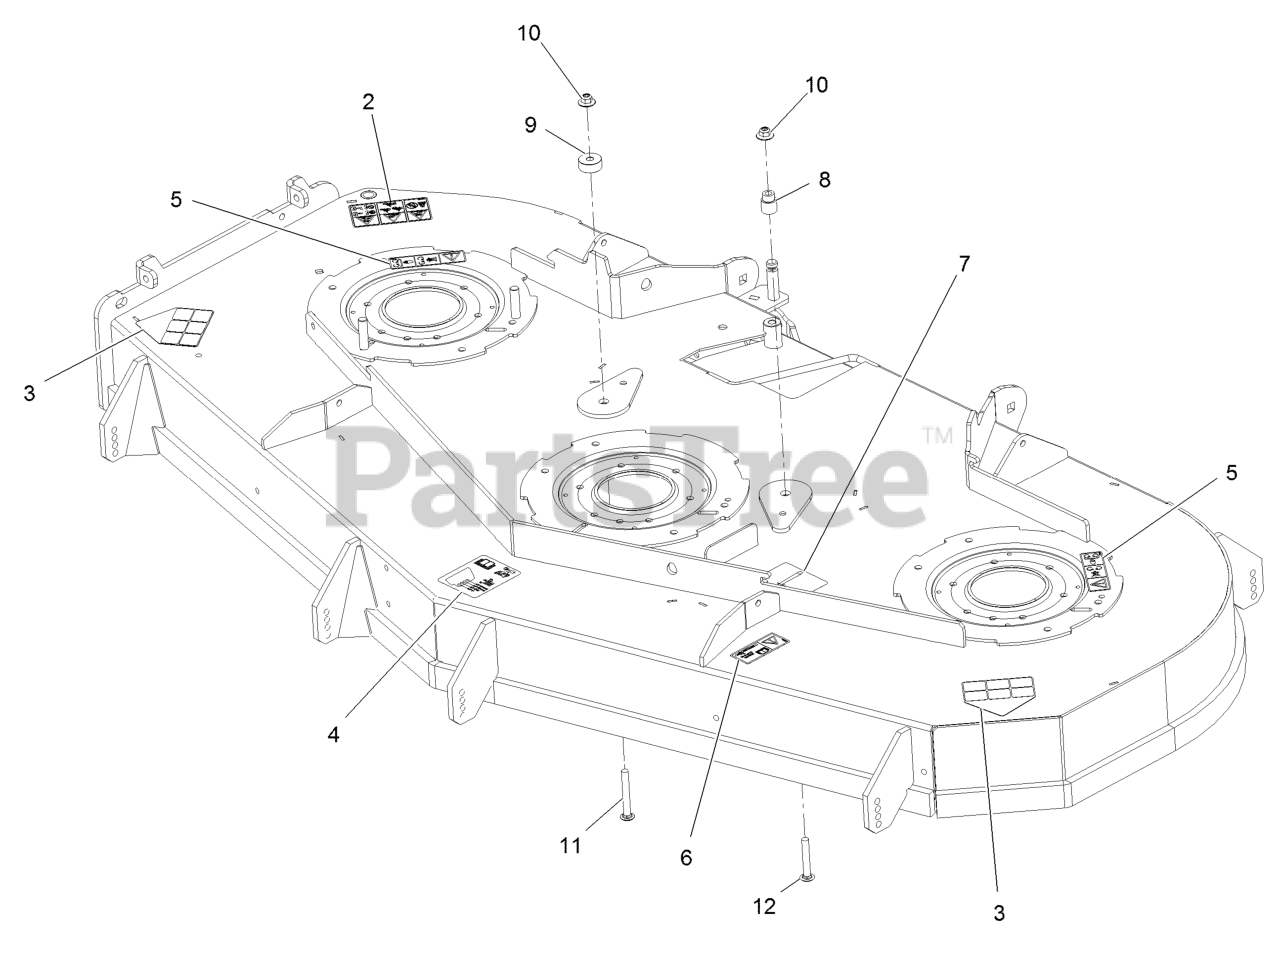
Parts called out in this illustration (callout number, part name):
2	DECAL-DANGER
3	DECAL-DANGER
4	DECAL-ROLLER, ANTI-SCALP
5	DECAL-COVER, MISSING
6	DECAL-BOLT TORQUE
7	DECAL-BELT ROUTING
8	BUSHING-IDLER
9	SPACER-IDLER
10	Nut-Nyloc 3/8-16 Flg
11	SCREW-CARR
12	SCREW-CARR
